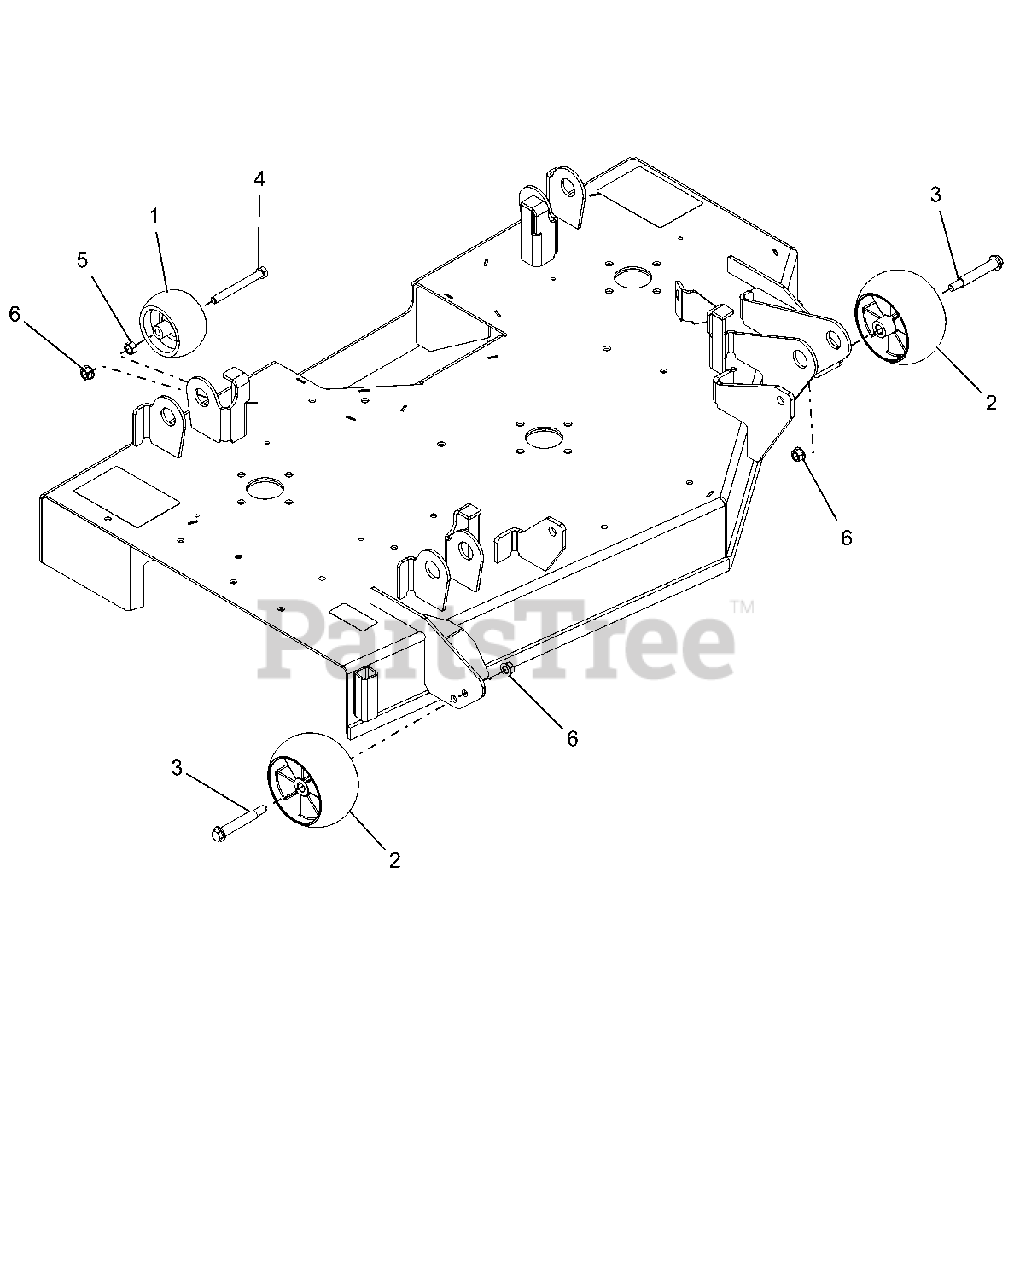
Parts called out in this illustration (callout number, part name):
2	ANTI-SCALP WHEEL - 5XOS
3	BLT-SHLDR .38-16X2.50 HWH G5YZ
4	BLT-HEX .38-16X3.50 GR5 YWZC
5	NUT-HEX .38-16 YWZC
6	NUT, LK-TOP-FLG .38-16 YWZC
